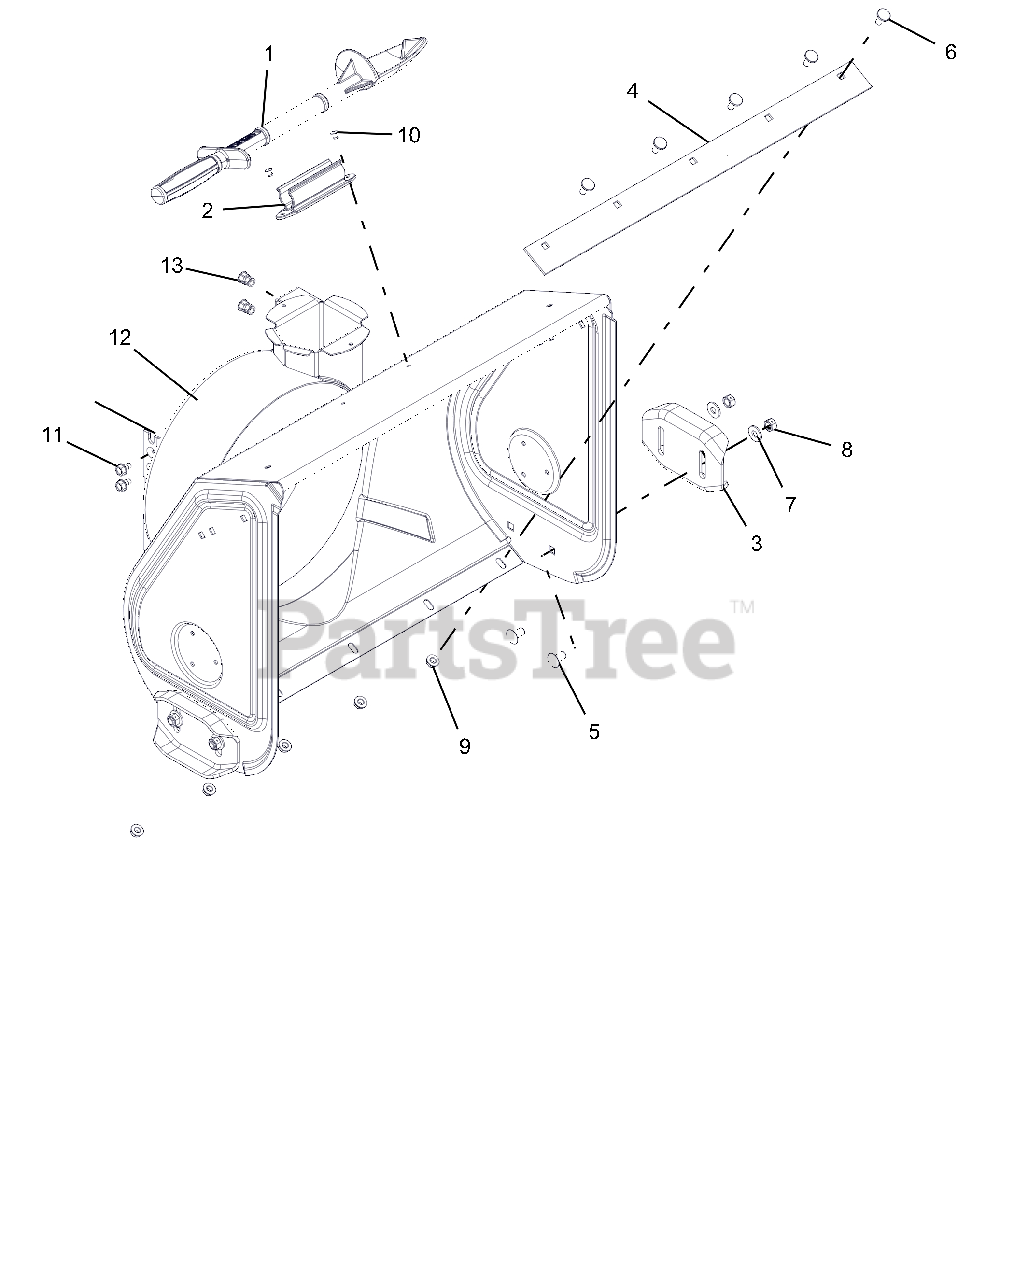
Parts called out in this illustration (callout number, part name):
1	DEVICE, SNOW CLEAN OUT
2	MOUNT, SNOW CLEAN OUT
3	SKID SHOE, REVERSIBLE - ORANGE
4	SCRAPER BLADE, 24" COMPACT HI
5	@BLT-RHDSSQNK .38-16X.75 G5YZ
6	BOLT, MODIFIED HEAD CARRIAGE
7	@WSHR-FL-STL.38X.875X.083 YWZC
8	@NUT-LK-CTR .38-16 YWZC
9	@NUT-LK-TOP-FLG .31-18 YWZC
10	RVT-POP .187 YZ
11	@SCR-TAP .31-18X.50 HWH TR YWZ
12	BLOWER HOUSING, 24" HI ORANGE
13	NUT, THREADED INSERT .38-16
